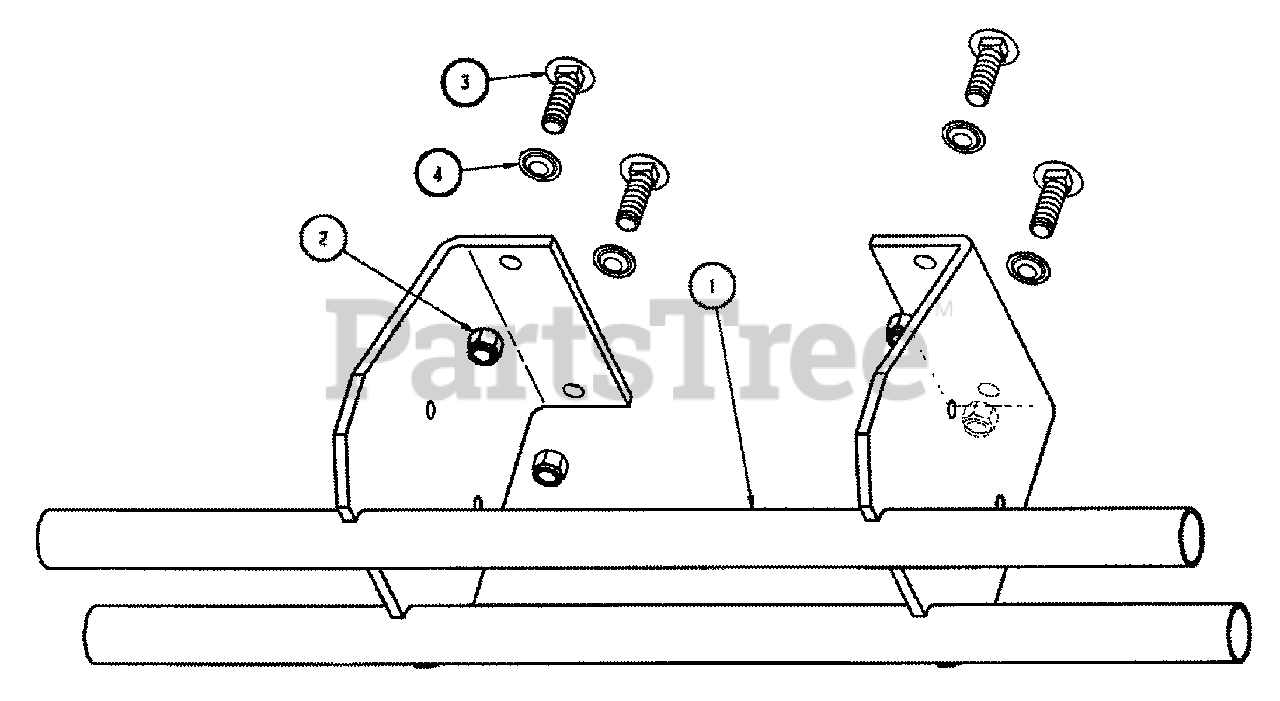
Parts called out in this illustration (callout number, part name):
1	WELDMENT,BUMPER
2	HNYL, 3/8-16, YZ
3	RHSSNB 3/8-16 X 1.25 YZ
4	BOLT RETAINER, 3/8
